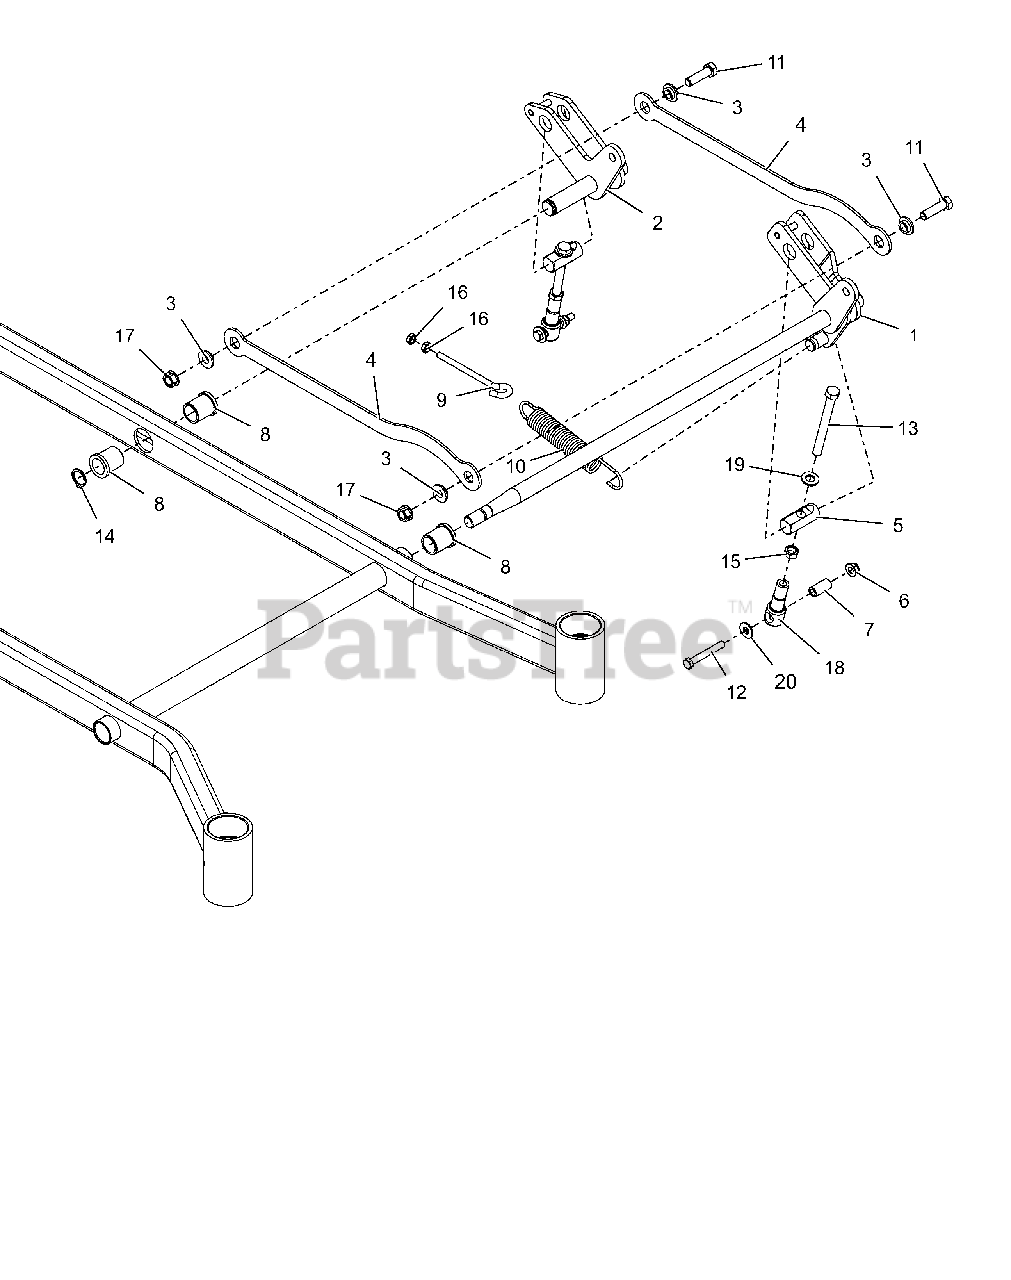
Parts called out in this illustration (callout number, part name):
1	FRT LH DECK LIFT ARM WMT- LF
2	WLDMT, REAR LH DECK ARM
3	BSHG-FLG .515X.750X.310X1.120
4	LINK, LIFT
5	PIN, DECK LIFT
6	@NUT-LK-NYL-FLG .38-16 YWZC
7	SPACER, DECK LEVELING
8	BSHG-FLG 1.00X1.25X1.50X1.50
9	BOLT,.38-16 X 4.25-.62 DIA EYE
10	SG-TENS .162X1.25X8.25 WLD 25
11	@BLT-HEX .50-13X1.75 GR5 YWZC
12	BLT-HEX .38-16X2.75 GR8 YWZC
13	BOLT, 1/2-13 X 5.0 2.5 THREAD
14	RG-RTNG-EXT 1.00X.078
15	NUT-JAM .50-13 YWZC
16	NUT-HEX-JAM .375-16 YWZC
17	NUT-LK-CTR-FLG .50-13 YWZC
18	LINK, DECK LIFT FORMED
19	FLATWASHER 1/2 SAE HARD 15906
20	@WSHR-FL-STL.438X1.00X.083 YWZ
